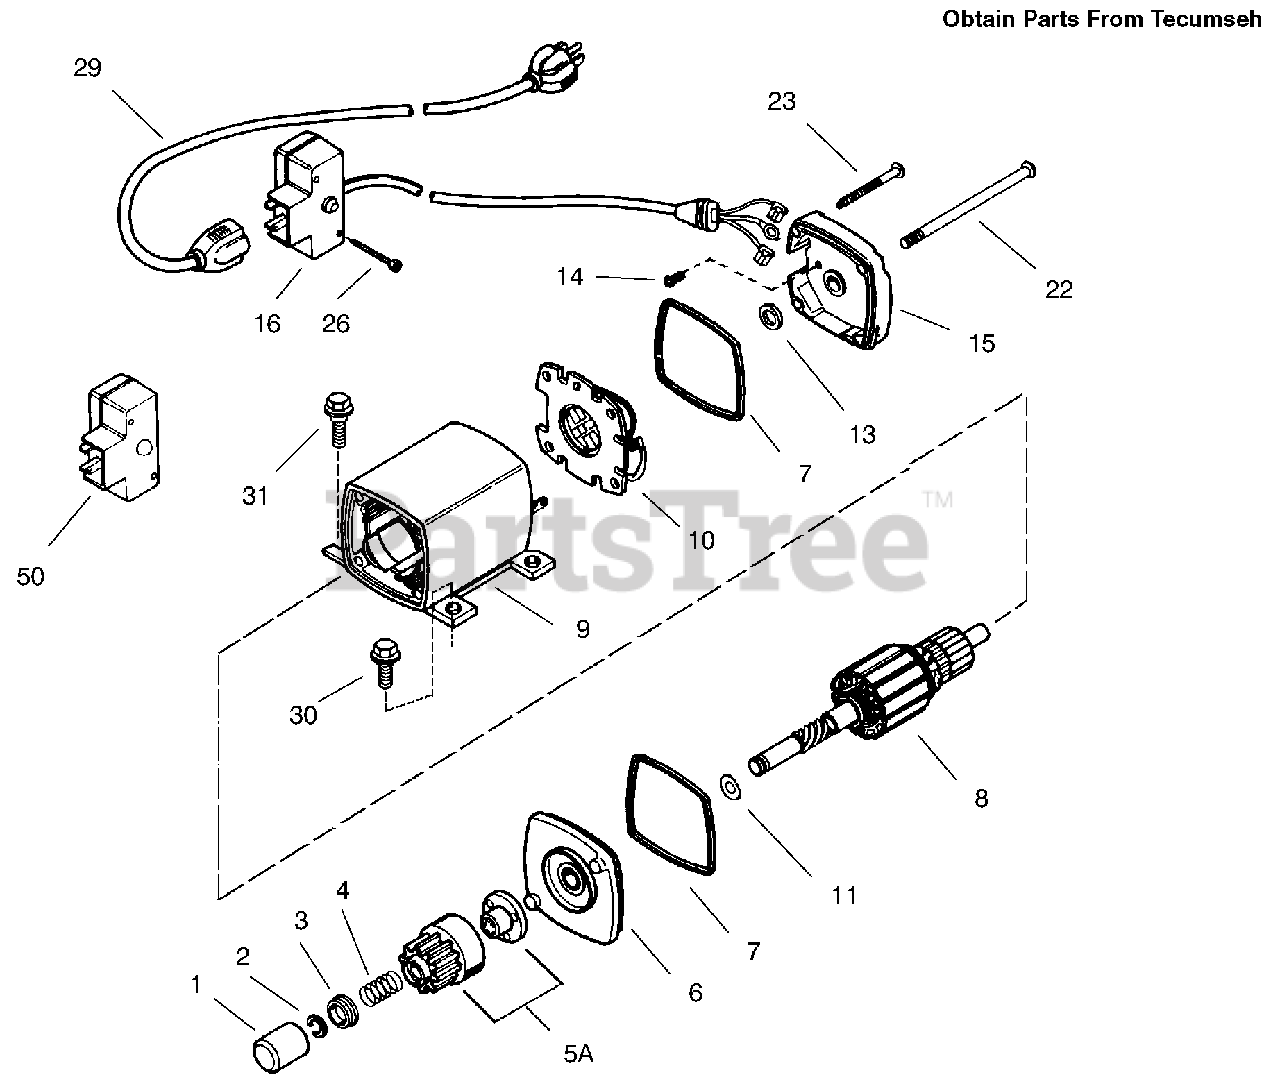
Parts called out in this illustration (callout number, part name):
1	Dust Cover
2	Retainer Ring
3	Spring Retainer
4	Anti-drift Spring
5A	Gear and Nut (Incl. Ref.# 2)
6	Drive End Cap Asm. (Incl. Ref.# 7)
8	Armature
9	Housing Assembly
10	Brush Card Assembly
11	Thrust Washer
13	Thrust Washer
14	Ground Screw
15	Commutator End Cap Asm. (Incl. Ref.# 7)
16	Switch Box Assembly (Incl. Ref# 26)
22	Case Bolt
23	Ground Screw
29	Extension Cord
30	Screw-Torx
50	Switch Repair Kit
